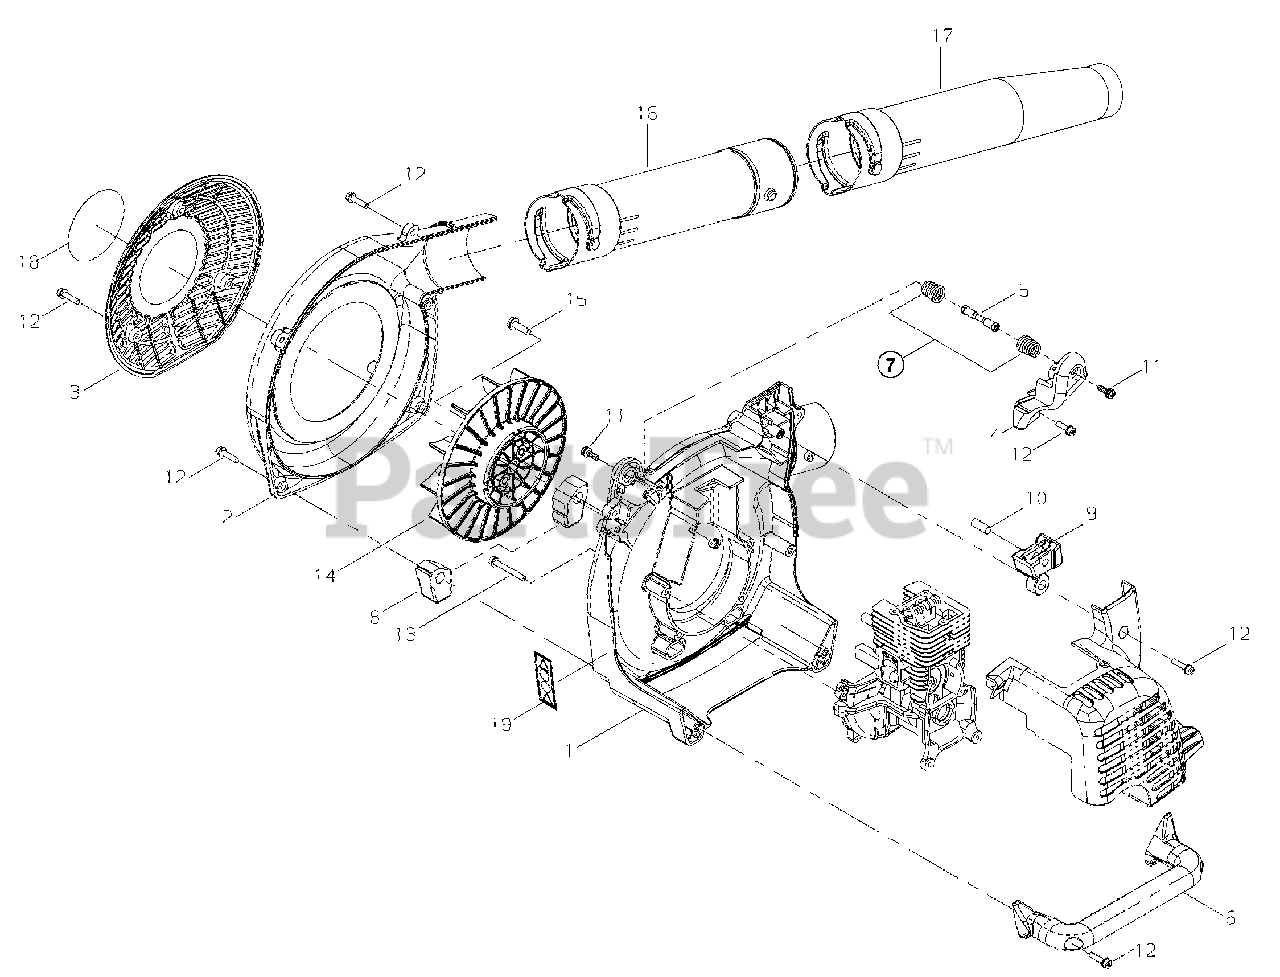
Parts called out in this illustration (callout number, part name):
1	COVER, FAN - RIGHT
2	COVER, FAN - LEFT
3	COVER, INTAKE
4	MOUNT, HANDLE
5	NUT, HANDLE 5
6	HANDLE, SIDE
7	SPRING, COIL Ø18ר14
8	CUSHION
9	CUSHION
10	PIN
11	SCREW, ADHESIVE M5×16
12	BOLT M5×20
13	BOLT M5×40
14	FAN
15	BOLT M6×20
16	PIPE
17	NOZZLE
18	LABEL, EB2510
19	LABEL, CAUTION
